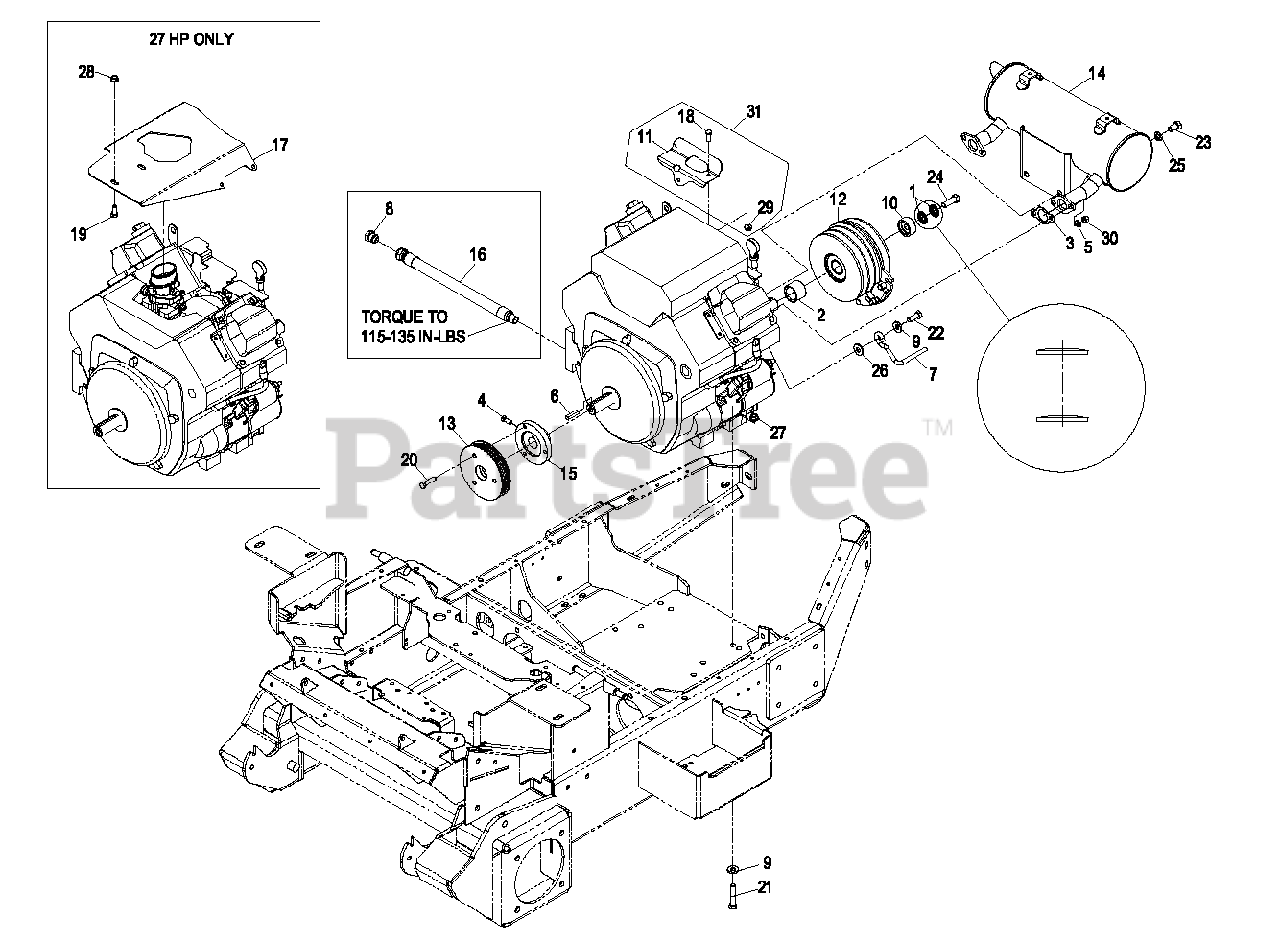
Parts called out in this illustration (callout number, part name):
1	WASHER-SPRING
2	SPACER-CLUTCH
4	SCREW-SET
5	WASHER-LOCK
6	KEY-SQUARE
7	ROD-BELT
8	PLUG
9	WASHER-BELLEVILLE
10	KEEPER-CLUTCH
11	CABLE HEAT SHIELD KIT
12	CLUTCH KIT
13	SHEAVE, 5K 4.63
14	KIT,MUFFLER KOHLER
15	HUB,ADAPTER (PLTD)
17	BRACKET, AIRCLNR FMZ-AC
18	SCREW-HH
19	SCREW-HH
20	SCREW-HH
21	SCREW-HH
22	SCREW-HH
23	SCREW-HH
24	SCREW-HH
25	SCREW-HH
26	WASHER-FLAT
27	NUT-HHF, WHIZ
30	NUT-HEX
31	CABLE HEAT SHIELD KIT
